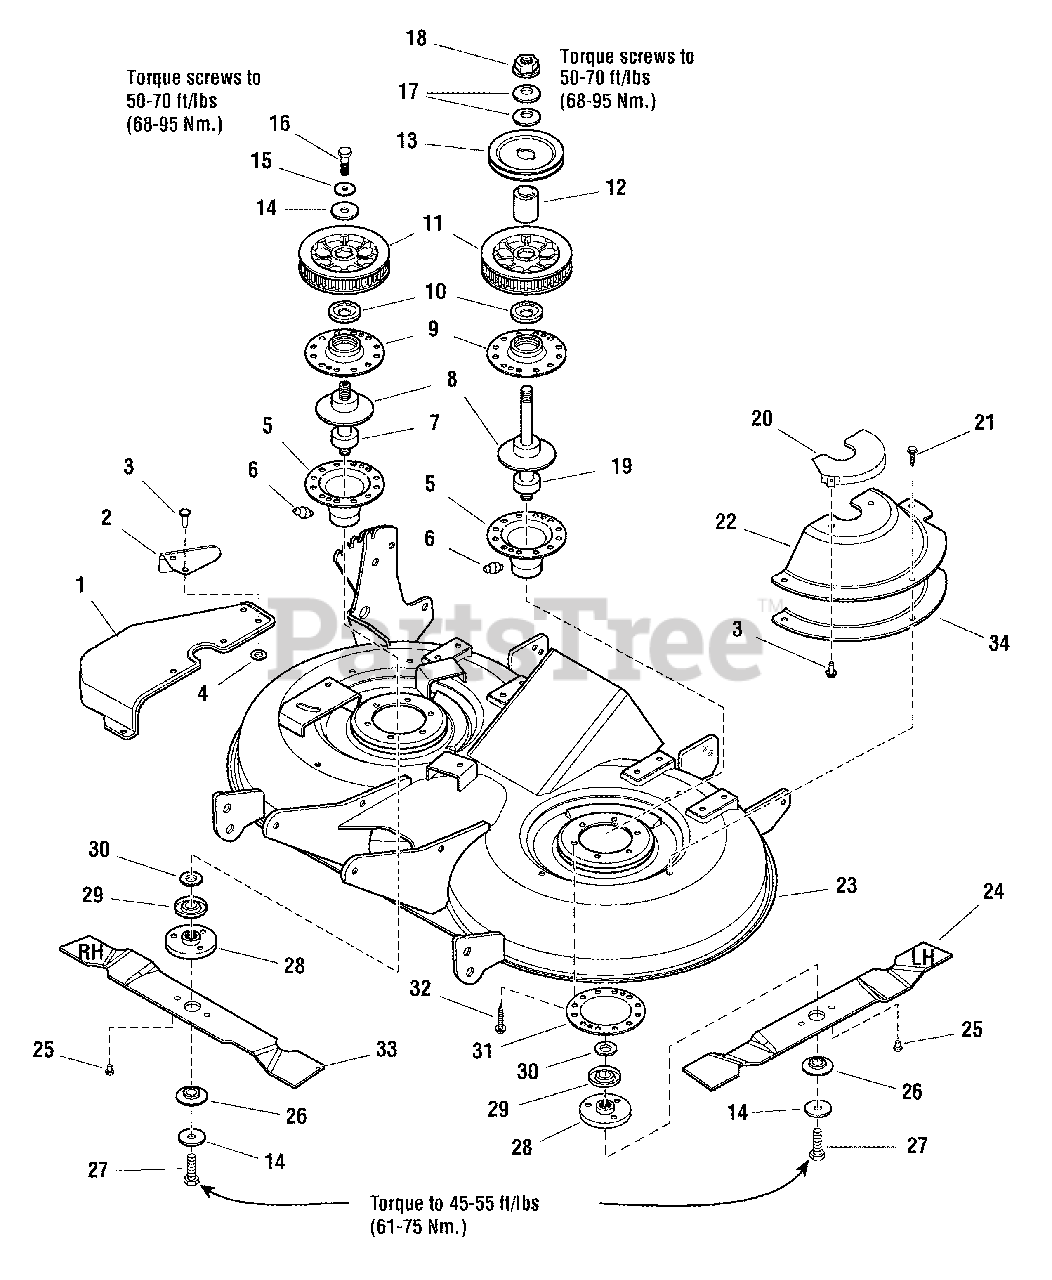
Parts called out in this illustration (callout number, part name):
1	COVER, Arbor, RH
2	GUARD, Extension
3	RIVET, Pop
4	WASHER
5	HOUSING, Arbor, Bottom w/Lube Fitting
6	FITTING, Lube
7	ARBOR SHAFT & BEARING ASSEMBLY
8	GASKET
9	HOUSING, Arbor, Top
10	SHIELD, Bearing
11	SPROCKET & FLANGE ASSEMBLY, 38 Tooth
12	HUB
13	PULLEY, Arbor 5" OD
13	PULLEY, Arbor 6" OD
14	WASHER, Spring
15	WASHER
16	CAPSCREW, Hex Head, 7/16-14 x 2-3/4, GR8
17	WASHER, Bellville, 9/16
18	NUT, Hex Flange, 9/16-18
19	ARBOR SHAFT & BEARING ASSEMBLY
20	GUARD & BRACKET ASSEMBLY, LH
21	CAPSCREW, Hex Head Taptite, 5/16-18 x 3/4
22	COVER, Arbor, LH
22	Cover, Arbor, LH
23	HOUSING ASSEMBLY, Red
24	BLADE, Mower LH, Mulching High Lift
25	PIN, Blade
26	WASHER, Spline
27	CAPSCREW, Hex Head, 7/16-14 x 2-1/4, GR8
28	ADAPTER, Blade
29	SHIELD, Bearing
30	WASHER, Shim
31	ADAPTER, Arbor
32	CAPSCREW, Hex Head Taptite, 5/16-18 x 1
33	BLADE, Mower RH, Mulching High Lift
34	SHIM, Cover LH
